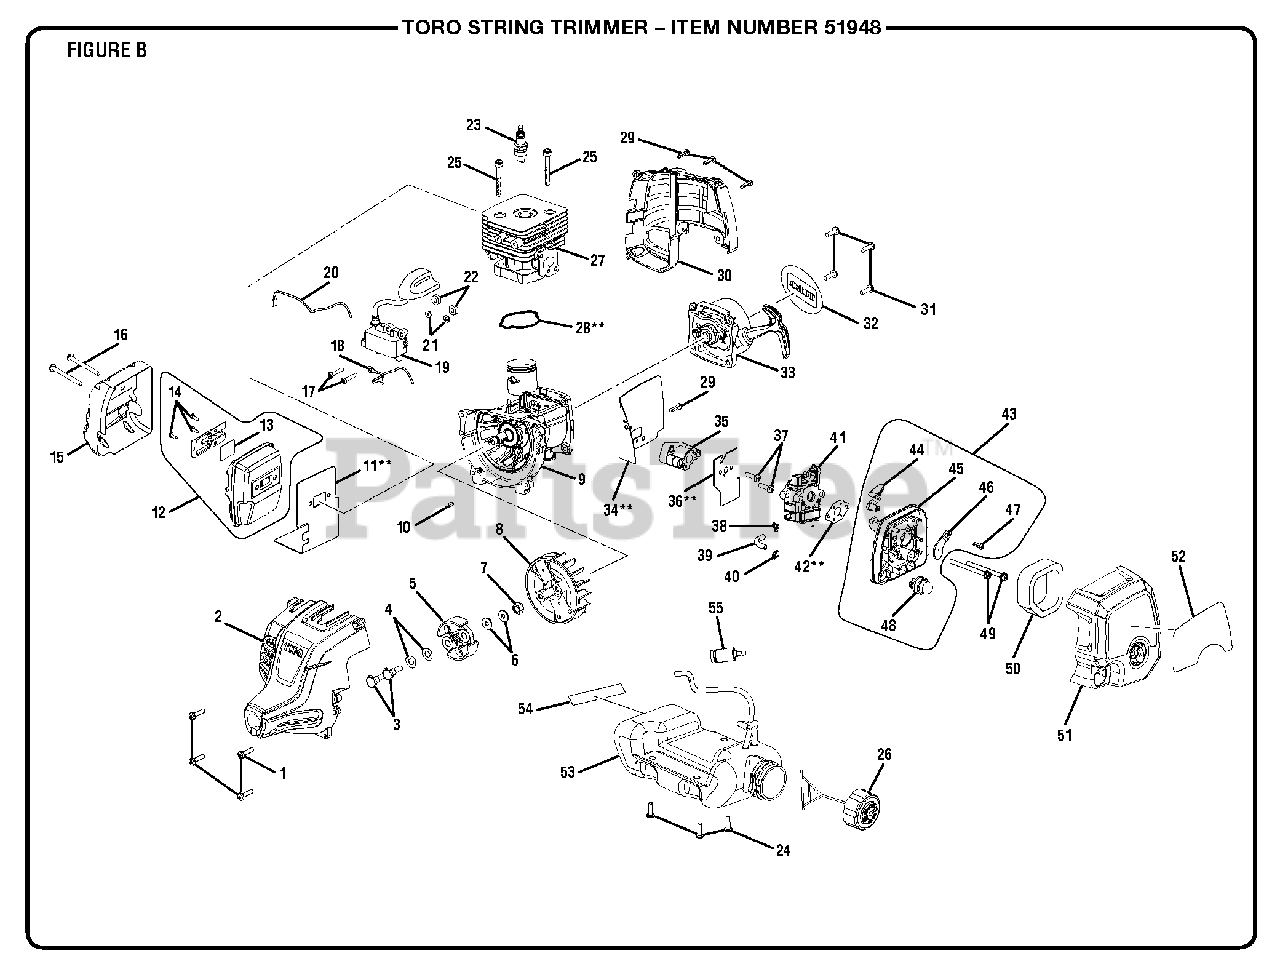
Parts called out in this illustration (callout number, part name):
1	Screw (M5 x 20 mm, T20 Torx Pan Hd.)
2	Front Housing Assembly
3	Clutch Shoulder Bolt (M6 x 22.5 mm, Hex Hd.)
4	Curved Washer
5	Clutch Assembly
6	Washer (ID6 x OD15 x 1.2t)
7	Flywheel Nut
9	Crankcase Assembly
10	Woodruff Key (10 mm x 3 mm)
11	Muffler Gasket
12	Muffler Assembly
13	Screen
14	Screw (6-20 x 1/4 in., T20 Torx Pan Hd. S.T.)
15	Heat Shield
16	Screw (M5 x 50 mm, T25 Torx Soc. Hd.)
17	Screw w/Washer (M4 x 19 mm, T20 Torx Soc. Hd.)
18	Lead Wire (Red)
19	Coil Boot Assembly
20	Lead Wire (Black)
21	Washer (ID4.2 x OD10 x1t)
22	Spacer (Phenolic)
23	Spark Plug (Champion RCJ4)
24	Screw (M5 x 16 mm, T25 Torx Soc. Hd.)
25	Screw (M5 x 22 mm, T25 Torx Soc. Hd.)
26	Fuel Cap Assembly
28	Gasket
29	Screw (M4 x 18 mm, T20 Torx Pan Hd. S.T.)
30	Rear Engine Housing
31	Screw w/Washer (M5 x 16 mm, T25 Torx Soc. Hd.)
32	Logo Label (Rear)
33	Starter Recoil & Starter Cup Assembly
34	Insulator Gasket
35	Heat Dam Insulator
36	Gasket
37	Screw w/Washers (M5 x 34 mm, T25 Torx Pan Hd.)
38	Hose Clip
39	Fuel Line (45 mm)
40	Hose Clip
41	Carburetor Assembly
42	Carburetor Gasket
43	Airbox Base Assembly
44	Choke Lever
45	Airbox Base
46	Choke Plate
47	Screw (M4 x 12 mm, T20 Torx Pan Hd. S.T.)
48	Primer Assembly
49	Screw (M5 x 60 mm, T25 Torx Cap Soc. Hd.)
50	Air Filter
51	Airbox Cover Assembly w/Label
52	Starting Instructions Label
53	Fuel Tank & Cap Assembly
54	Combustion Warning Label
55	Fuel Filter
